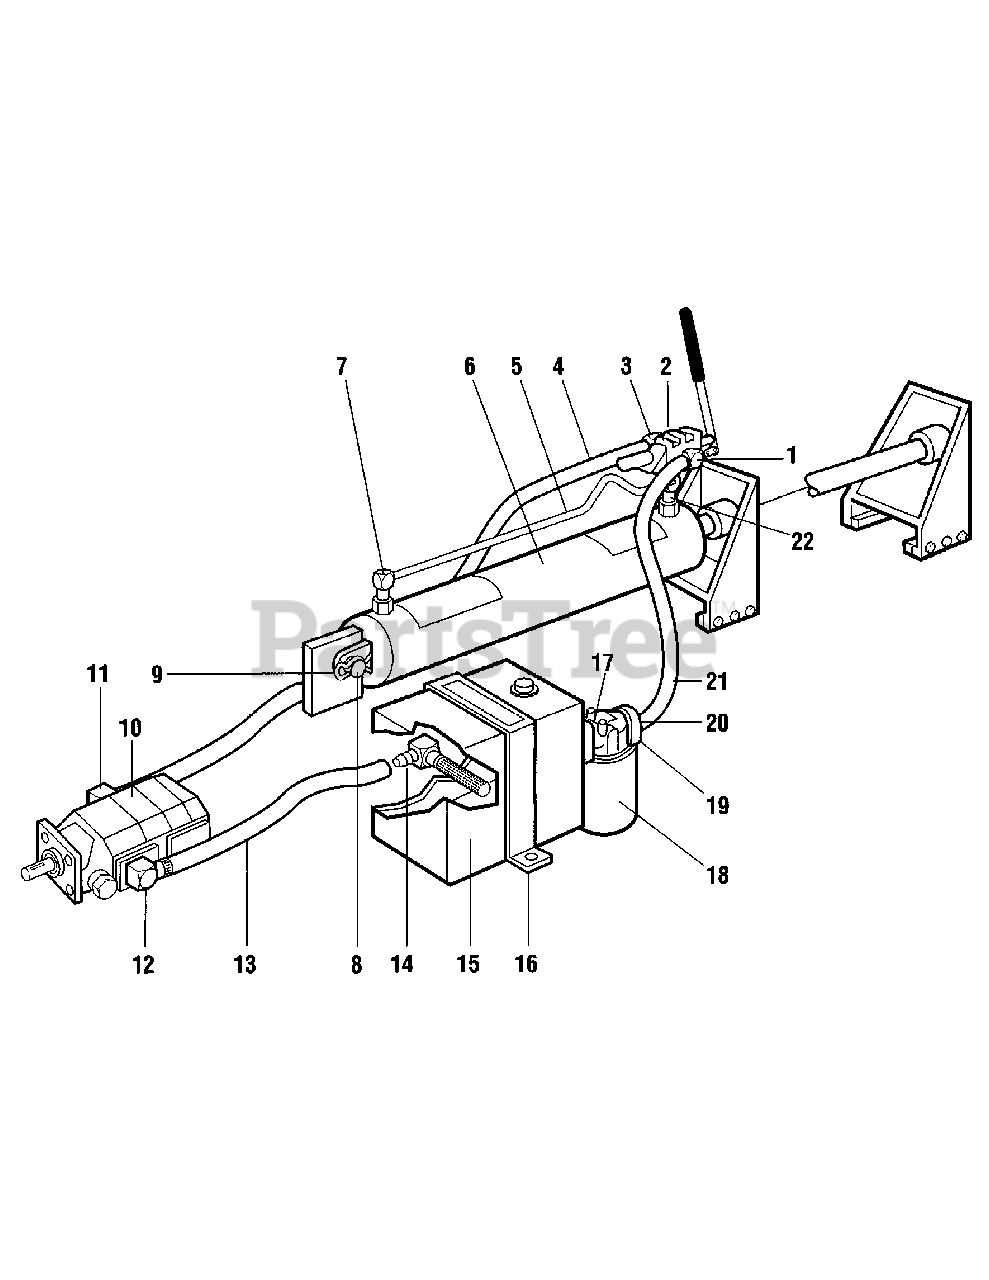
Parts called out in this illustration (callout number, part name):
1	Fitting 90 deg. hose barb
2	Valve
3	Fitting 90 deg. Male
4	HP Hose
5	Formed Tubing 21-1/16"
6	Cyliner 3-1/2" TMC
7	Fitting 90 deg. male
8	Clevis Pin for cylinder
9	Clevis Pin Clip for cyl.
10	Barnes 11 GPM Pump
11	Fitting 90 deg. Female
12	Fitting 90 deg. Beaded hose barb
13	LP Hose 3/4" ID x 25" (connects pump to tank)
14	Strainer & hose barb
15	Plastic Tank
16	Tank Strap
17	Pipe blk Nipple 3/4 x 2
18	Filter Element
19	Filter Housing
20	Fitting beaded hose barb
21	LP Hose 3/4" ID x 17"
22	Straight Male Connector
